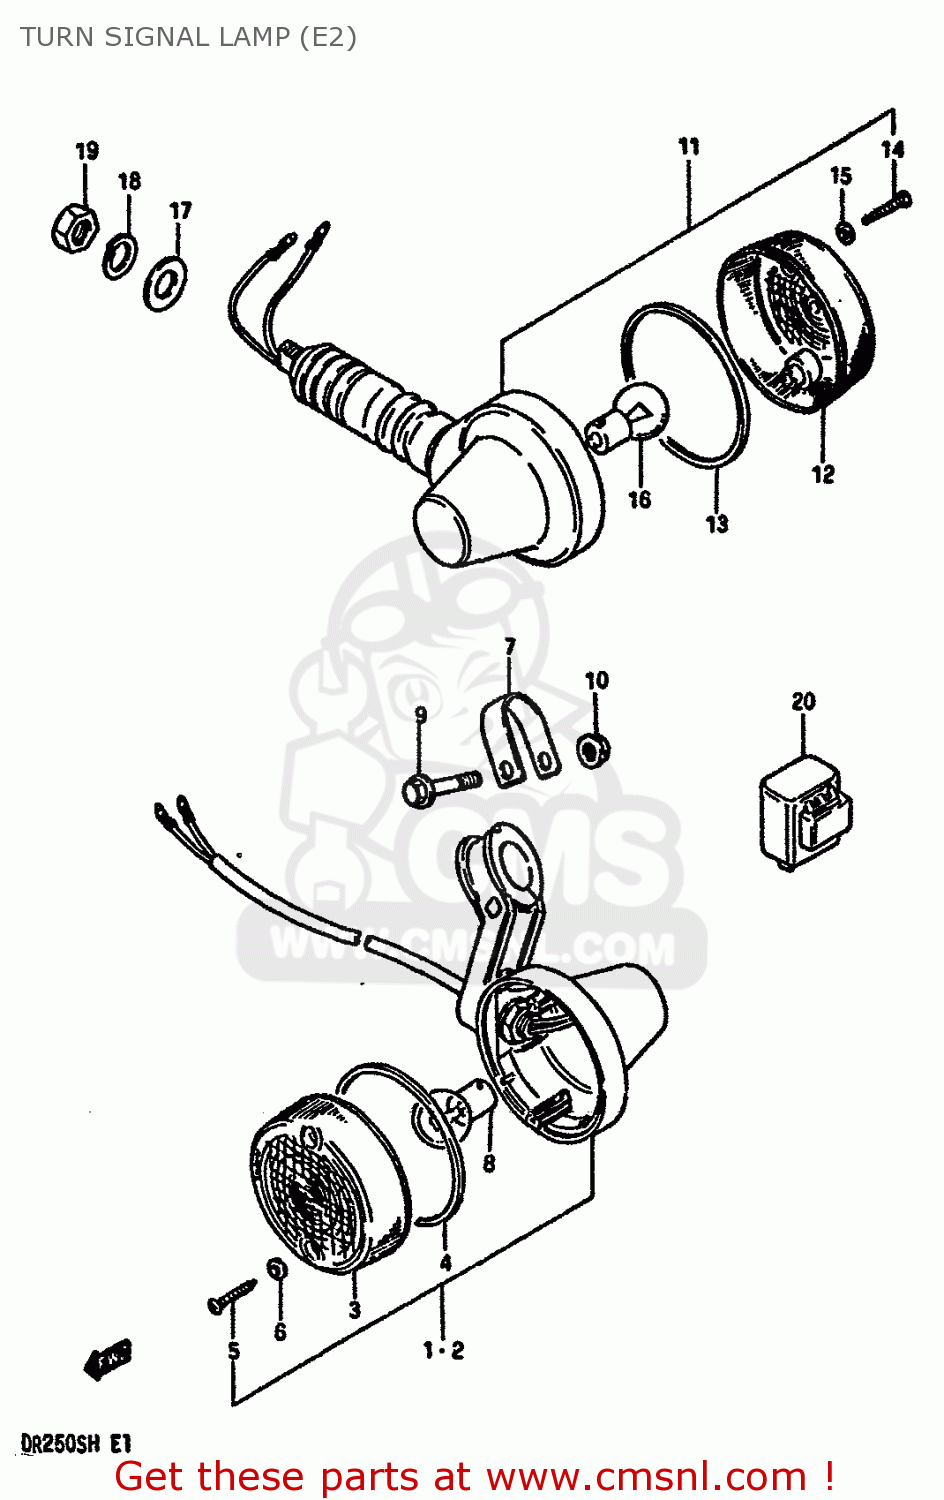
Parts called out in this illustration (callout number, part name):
1	LAMP ASSEMBLY,FRONT TURN SIGNAL
2	LAMP ASSEMBLY,FRONT TURN SIGNAL
3	LENS
4	GASKET (NAS)
5	SCREW TAPP.
6	GASKET (NAS)
7	PLATE
8	BULB(12V21W)
9	BOLT 5X42
10	NUT ,5MM
11	LAMP,REAR TURN SIGNAL
12	LENS
13	GASKET (NAS)
14	SCREW TAPP.
15	GASKET (NAS)
16	BULB(12V21W)
17	WASHER
18	WASHER,LOCK 12
19	NUT
20	RELAY ASSEMBLY,TURN SIGNAL
